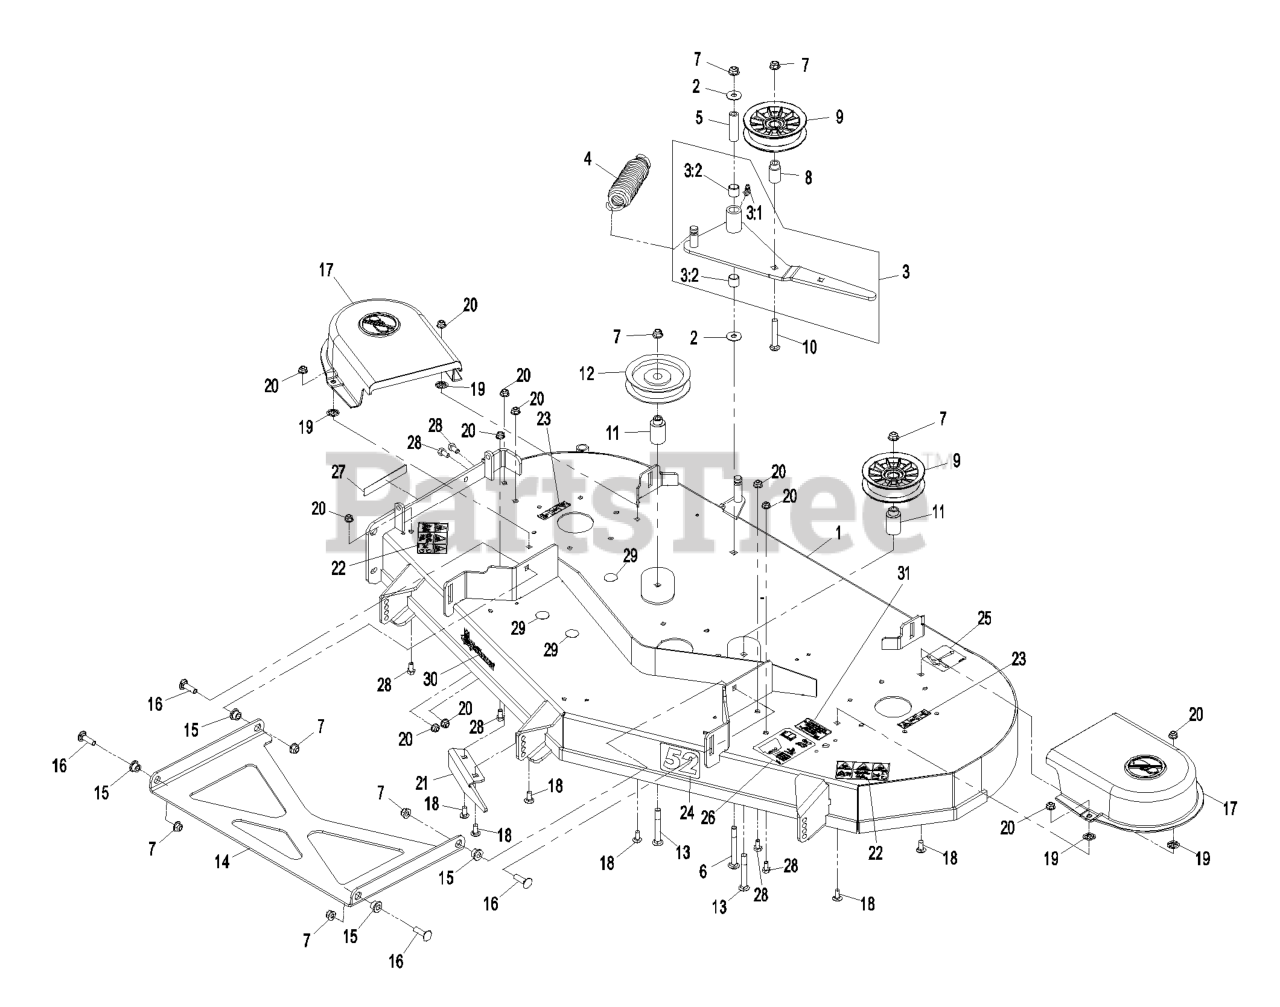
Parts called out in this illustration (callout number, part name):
1	52 INCH DECK ASM
3	IDLER ARM ASM
3:1	FITTING-GREASE, 90 DEG
3:2	SLEEVE-BEARING
5	BUSHING-PIVOT, IDLER
6	SCREW-CARR
7	NUT-HF, NI
8	BUSHING-IDLER
9	SHEAVE AND BEARING ASM
10	SCREW-CARR
11	BUSHING-IDLER
13	BOLT-CARRIAGE
14	STRUT-DECK
15	BUSHING-FLANGED
16	BOLT-CARR
17	SHIELD-BELT
18	SCREW-CARR
19	RING-RETAINING, BOLT
20	NUT-HF, NI
21	BAFFLE-DISCHARGE
22	DECAL-DANGER
23	DECAL-WARNING, BELT SHIEL
24	DECAL,DECK 52
25	DECAL-ROUTING, BELT
26	DECAL-ROLLER, ANTI-SCALP
27	DECAL-DANGER
28	SCREW-HH
29	DECAL-HOLE COVER
31	DECAL,BLADE TORQUE
